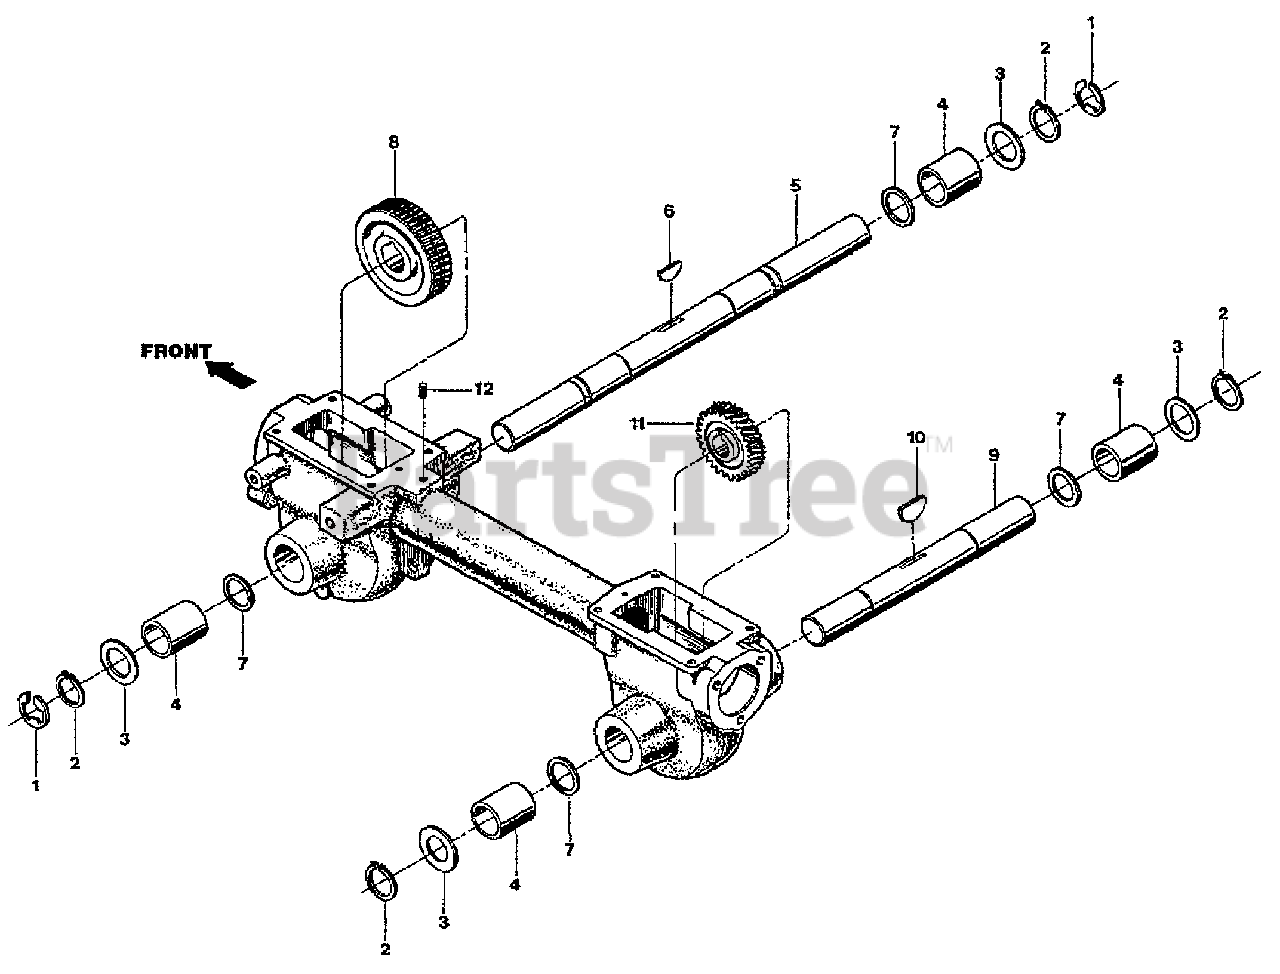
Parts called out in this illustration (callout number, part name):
1	Retainer, Snap Ring, "E" Type
2	Retainer, Snap Ring
3	Shim, 0.062 Thick
4	Bushing, Bronze
5	Wheel Shaft
6	Hi-Pro Key, 1/4 x 1
7	Spacer
8	Worm Gear, Wheel Shaft
9	Tiller Shaft
10	Woodruff Key
11	Worm Gear
